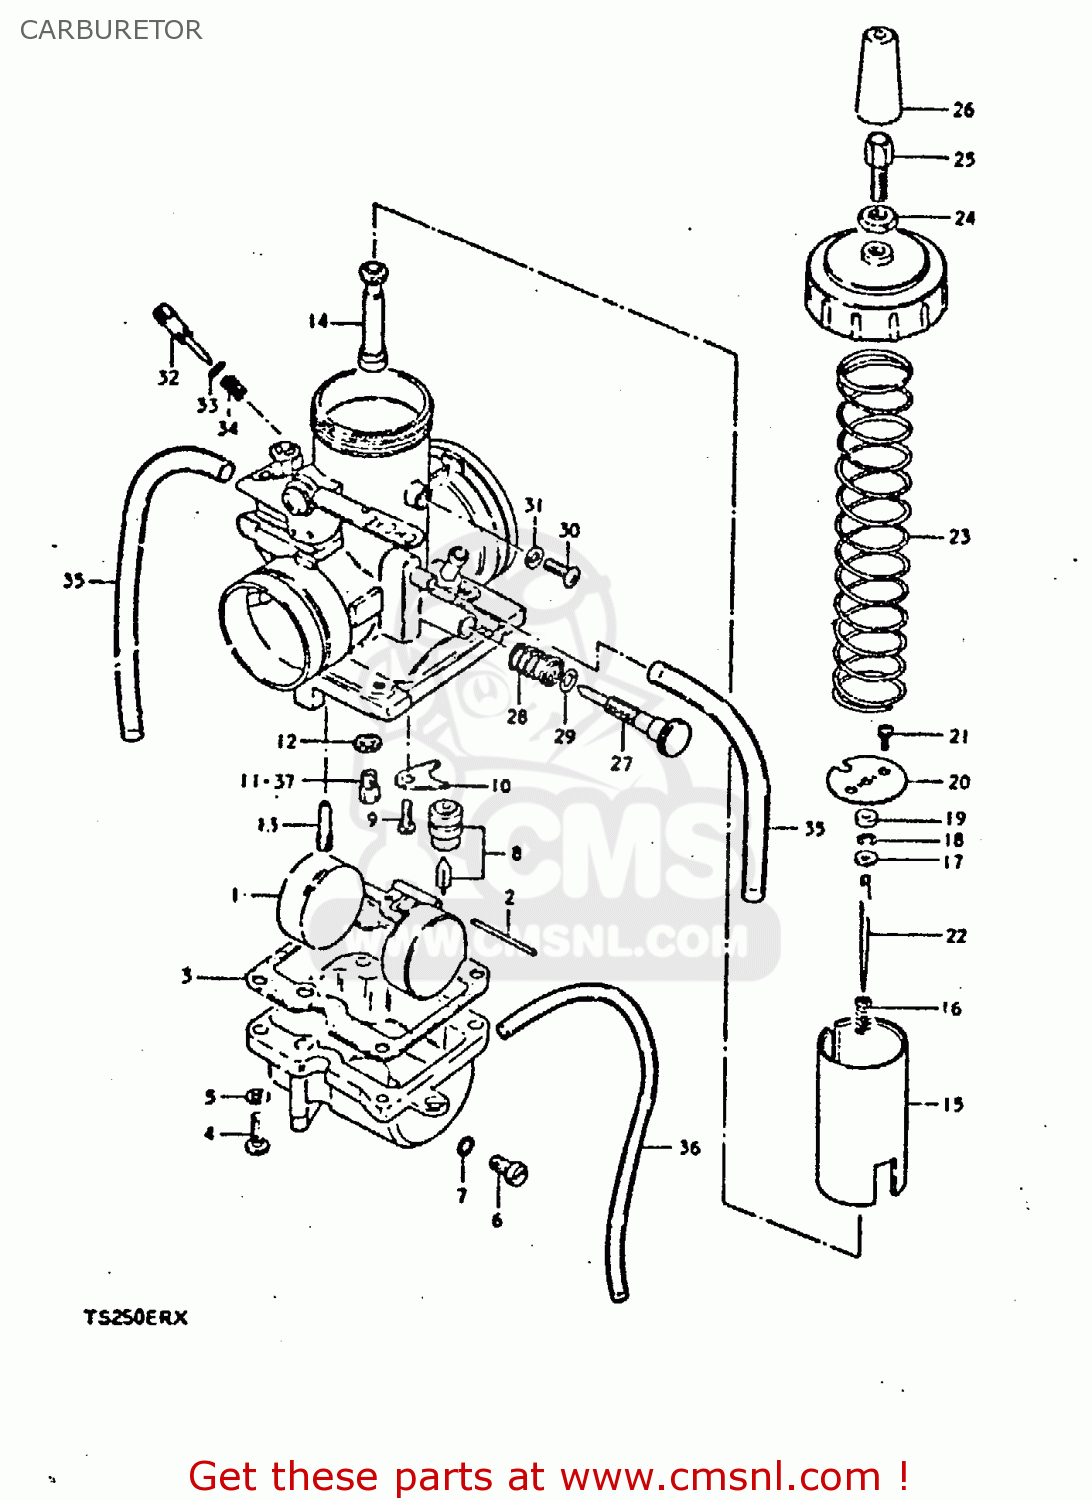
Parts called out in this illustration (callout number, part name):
1	FLOAT
2	PIN,FLOAT
3	GASKET,FLOAT CAHMBER (NAS)
4	SCREW
5	LOCK WASHER
6	PLUG
7	GASKET,DRAIN,PLUG (NAS)
8	VALVE ASSEMBLY,NEEDLE
9	SCREW
10	PLATE
11	JET
12	WASHER
13	JET
14	JET,NEEDLE
15	VALVE,THROTTLE
16	SPRING
17	WASHER,JET NEEDLE
18	CLIP
19	RING
20	PLATE
21	SCREW
22	NEEDLE,JET
23	SPRING, THROTTLE VALVE
24	NUT
25	ADJUSTER,CABLE
26	CAP
27	ADJUSTER
28	SPRING
29	O-RING
30	SCREW
31	RING
32	SCREW,PILOT AIR
33	O RING
34	SPRING
35	HOSE
36	HOSE
37	JET
